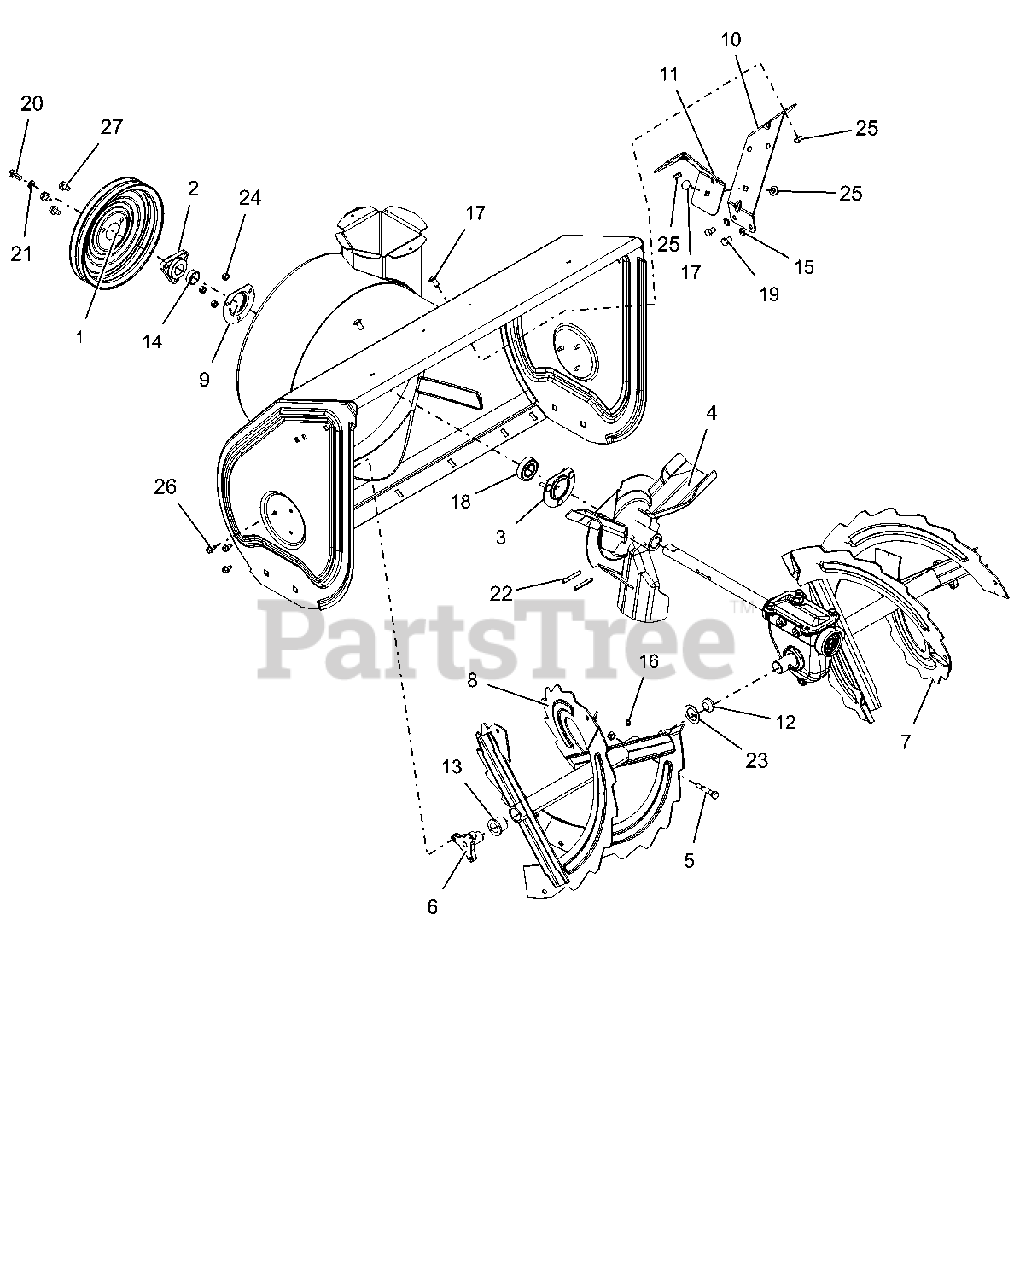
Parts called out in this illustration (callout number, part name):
1	PULLEY, SPIN FORM DUAL GROOVE
2	PULLEY HUB, D-BORE .87 DELUXE
3	BEARING FLANGE
4	IMPELLER, 3 BLADE-14"
5	SHEAR BOLT SERVICE ASSEMBLY
6	SUPPORT, RAKE BUSHING
7	RAKE, LH W/ZERK - 30"
8	RAKE, RH W/ZERK - 30"
9	BEARING FLANGE
10	BRACKET, GEARCASE SUPPORT - LH
11	BRACKET, GEARCASE SUPPORT - RH
12	PLUG, RAKE TUBE
13	BSHG-FLG, NY.778 ID X 1.018 OD
14	BSHG-SPCR .895IDX1.065ODX.353
15	@WSHR-LK-EXT.326X.599X.031YWZC
16	ZERK,FITTING .25X.125 DRIVE IN
17	BLT-RDHDSQSHNK.31-18X.62 YZ-LK
18	BRG-BALL .876 X 1.750 X .50
19	@BLT-HEX .31-18X.50 GR5 YWZC
20	BLT-HEX .31-24X.75 YWZC GR5
21	WSHR-LK .312X.097 HVY YWZC
22	PIN-ROLL .250X1.75
23	WSHR-FL-STL 1.010X1.505X.062YZ
24	@NUT-LK-CTR .25-20 YWZC
25	@NUT-LK-TOP-FLG .31-18 YWZC
26	SCR-TAP .25-20X.50 HWH TR YWZ
27	@SCR-TAP .31-18X.50 HWH TR YWZ
